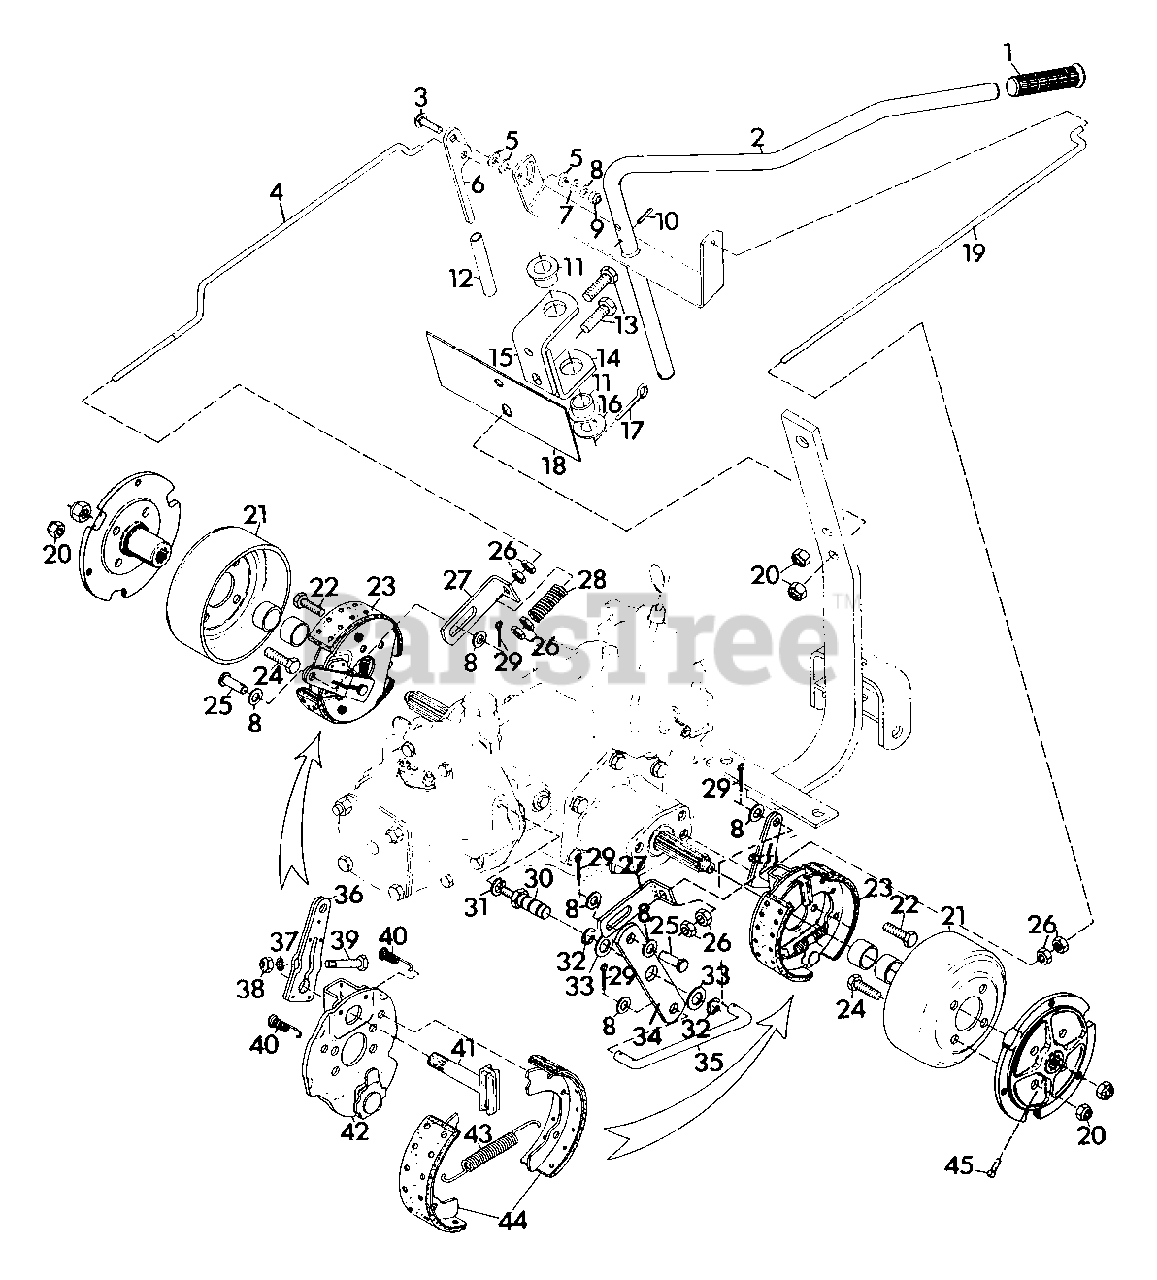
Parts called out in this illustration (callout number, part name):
1	Grip, Handlebar
2	Weldment, Brake Handlebar
3	Bolt, 3/8-16x1.50 Rd lid Sq Nk
4	Rod, Brake
5	Washer, Nylon .375x.75x.060
6	Handle, Parking Brake
7	Washer, Rubber .375x.75x.125
8	Washer, Flat .406x.812x.065
9	Nut, Lock 3/8-16
10	Pin, Spring .37.x2.00
11	Bushing, Pivot
12	Grip, Brake Handle
13	Bolt, Hex 1/2-13x2.04
14	Bracket, Brake Handle
15	Bracket, Brake Handle
16	Washer, Flat 1.063x2.000x.634
17	Pin, Cotter .188x1.500
18	Plate, Instruction
19	Rod, Brake L.H.
20	Nut, Lock 1/2-13
21	Drum, 7x1.75
22	Bolt, Hex 3/8-16x.875
23	Brake, 7x1.75 Mechanical
24	Bolt, Hex 1/2-7.3x1.375
25	Pin, Clevis .375x.750
26	Nut, Jam 3/8-16
27	Bracket, Adjustment
28	Spring, Compression
29	Pin, Cotter .09x.75
30	Stud, Pivot
31	Washer, Lock 1/2 Reg.
32	E-Ring, .625 Shaft
33	Washer, Flat .656x1.312x.095
34	Plate, Pivot
35	Rod, Brake Link
36	Arm, Cam Lever
37	Washer, Lock 5/16 Reg.
38	Nut, Hex 5/16-24
39	Bolt, Hex 5/16-24x1.75
40	Spring, Shoe Retaining
41	Cam, Brake
42	Plate, Back
43	Spring, Shoe Return
44	Kit, Brake Shoe
45	Screw, Set 7/16-14x.75 CPSH
NS	Clamp, Muffler
